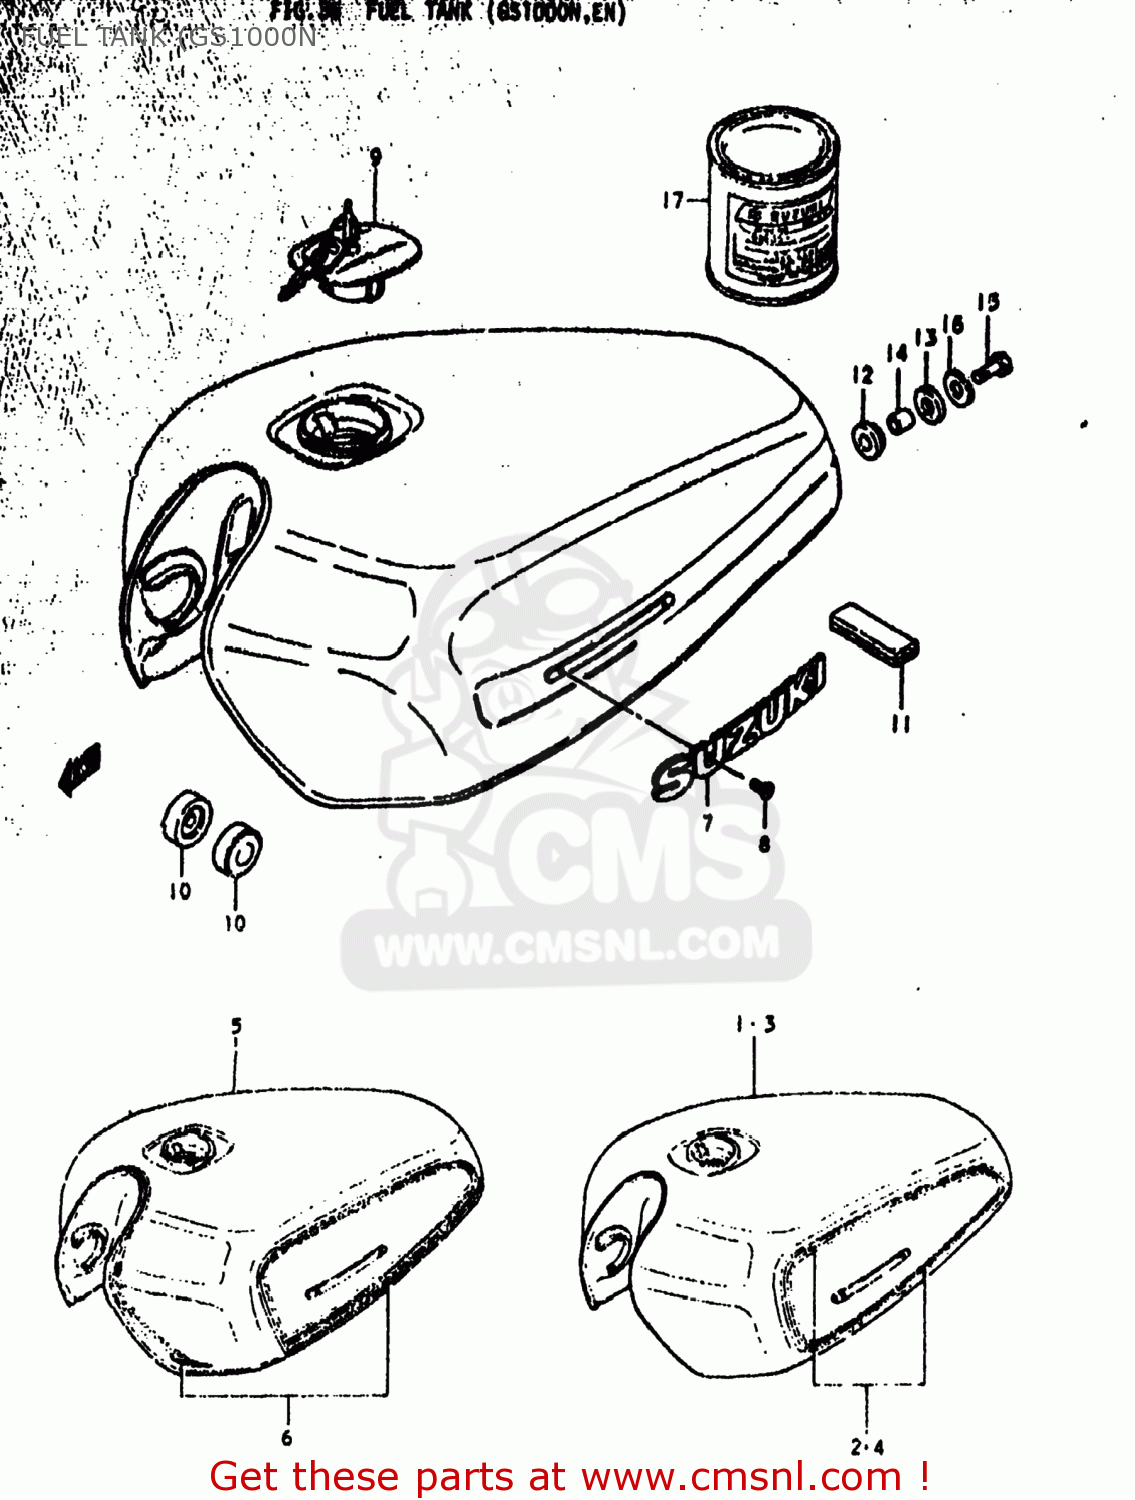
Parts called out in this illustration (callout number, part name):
1	TANK ASSEMBLY,FUEL
3	TANK ASSEMBLY,FUEL
5	TANK ASSEMBLY,FUEL
6	TAPE SET
7	EMBLEM,FUEL TANK
8	SCREW 3X6
9	CAP SET,FUEL TANK
10	CUSHION
11	CUSHION
12	CUSHION
13	CUSHION
14	SPACER(8.5X12X19)
15	BOLT (8X30)
16	WASHER (8.5X29X1.6)
17	PAINT,BLACK
